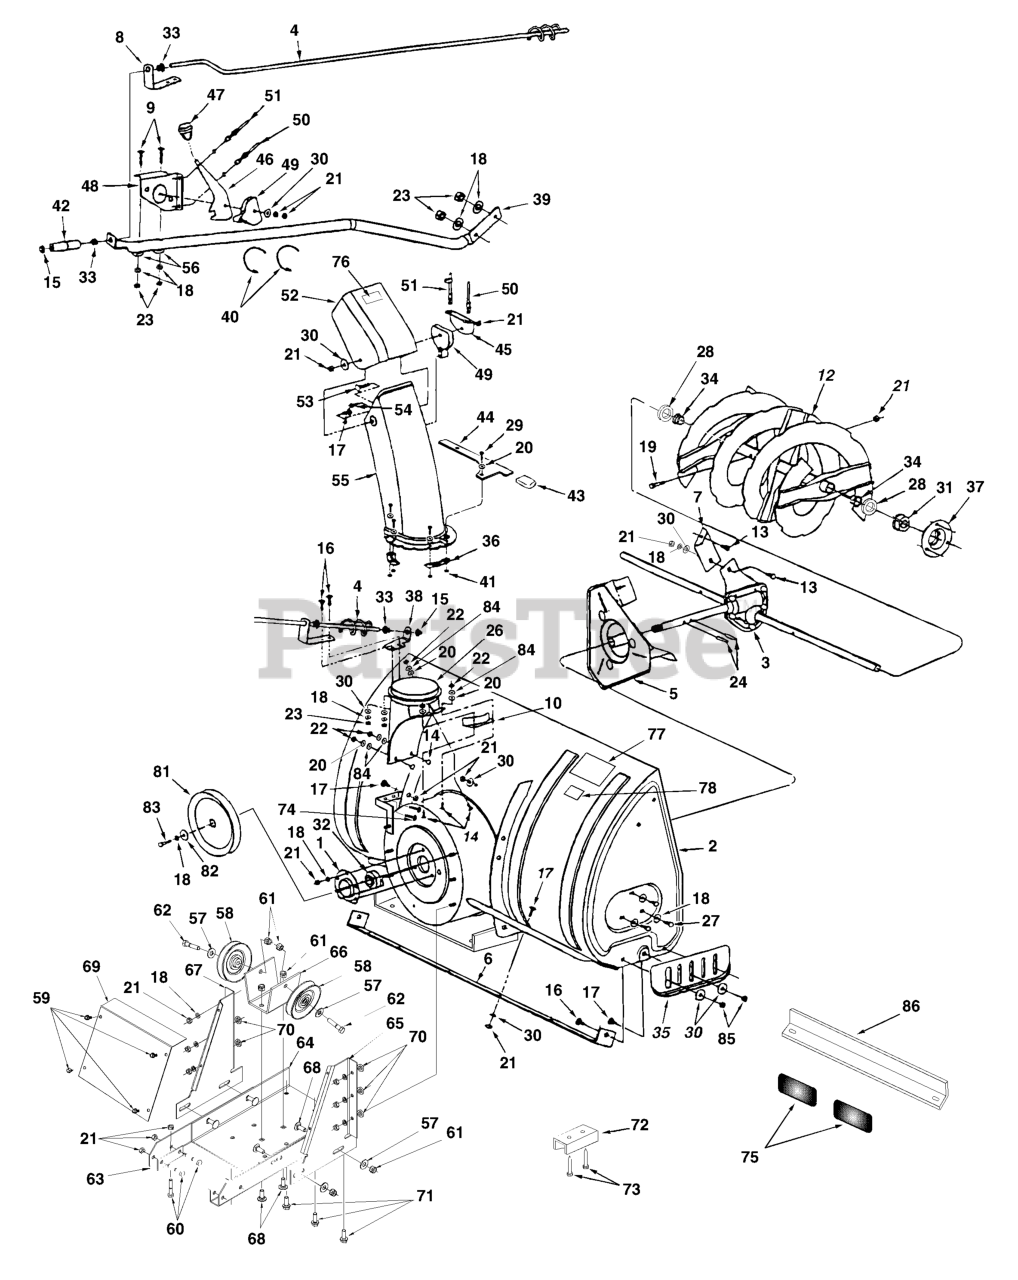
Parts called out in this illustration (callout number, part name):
1	Bearing Housing
2	Housing Assembly
3	Worm Drive Assembly
4	Chute Crank Rod Assembly
5	Impeller Assembly
6	Plate, Scraper 40"
7	Bracket, Housing Brace
8	Bracket, Chute Crank
9	Carriage Bolt, 5/16-18 x 1-3/4"
10	Chute Reinforcement
12	Spiral Auger Assembly, RH
13	Hex Bolt, 5/16-18 x 3/4"
14	Carriage Bolt, 1/4-20 x 3/4"
15	Palnut, 3/8"
16	Carriage Bolt, 5/16-18 x 1"
17	Carriage Bolt, 5/16-18 x 3/4"
18	Lockwasher, 5/16"
19	Shear Bolt, 5/16-18 x 1-1/2"
20	Washer, 1/4" Std Wrt
21	Hex Lock Nut, 5/16-18
22	Hex Lock Nut, 1/4-20
23	Hex Nut, 5/16-18
24	Spiral Pin, 1/4" Dia x 1-1/2"
26	Chute Adapter
27	Bolt, Self-tap 5/16-18 x 3/4"
28	Washer, Flat .76 x 1.49 x .06
29	Hex Bolt, 1/4-20 x 1"
30	Washer, 5/16" Std. Wrt.
31	Flange Bearing, .75" ID
32	Ball Bearing, .75" ID x 1.85" OD
33	Bushing, 3/8" Plastic
34	Split Bearing, 3/4"
35	Skid Shoe
36	Chute Keeper
37	Bearing Housing
38	Bracket, Chute Crank
39	Tube, Crank Rod Support
40	Nylon Tie
41	Lock Nut, 1/4-20 Washer Face
42	Crank Knob
43	Grip, Knob
44	Bracket, Chute Anti-rotation
45	Cable Bracket
46	Chute Tilt Handle
48	Chute Tilt Bracket Assembly
49	Guide, Cable
50	Cable, Chute Control
51	Cable, Chute Control W/Clip
52	Chute, Upper (Snow Deflector)
53	Carriage Bolt, 5/16-18 x 1-1/2"
54	Screw, 1/4-14 x 5/8"
55	Chute, Lower
56	Washer, Bowed
57	Washer, 3/8" Std Wrt
58	Pulley, V Idler
59	Screw, Self-tap 1/4" x 1"
60	Hex Bolt, 5/16-18 x 1-3/4"
61	Hex Lock Nut, 3/8-16 (Nylock)
62	Hex Bolt, 3/8-16 x 1-3/4"
63	Bracket, Lift Channel
64	Mounting Pan Assembly
65	Bracket, Housing Support (RH)
66	Bracket, Idler Pulley
67	Bracket, Housing Support (LH)
68	Carriage Bolt, 3/8-16 x 1"
69	Cover, Belt Drive
70	Bushing
71	Screw, 3/8-16 x 1-1/4" Thd Form
72	Bracket, Ramp Anchor
73	Screw, Hex Head Lag
74	Carriage Bolt, 5/16-18 x 1-1/4"
75	Red Reflector
76	Label, Cut Finger
77	Label, Warning/Danger
78	Label, Add Weight
81	Pulley, 7" OD
82	Washer, .344" ID X 1.125" OD
83	Hex Bolt, 5/16-24 x 1"
84	Washer, Nylon
85	Hex Lock Nut, 5/16-18 (Nylock)
86	Plate, Tail Reflector
